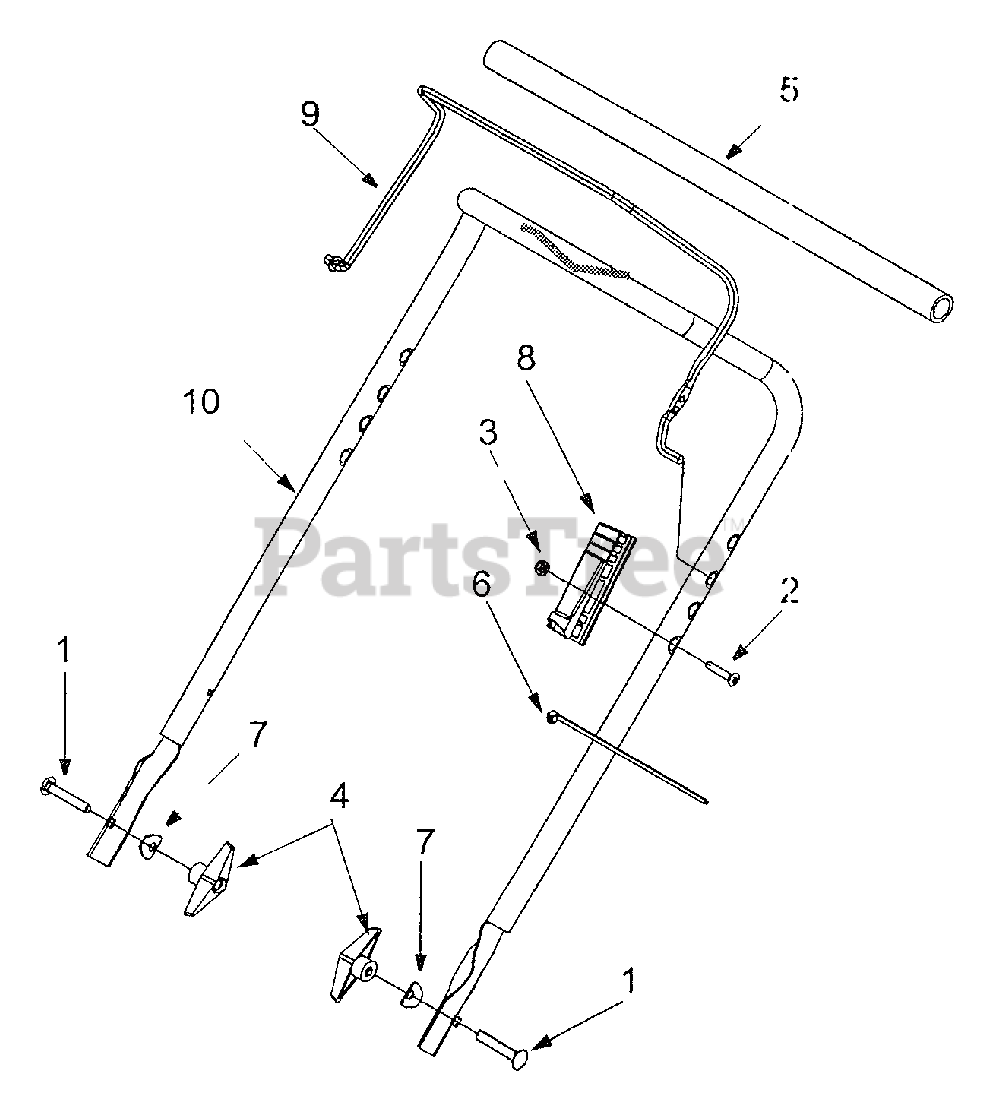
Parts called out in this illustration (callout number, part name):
1	Carriage Screw 5/16-18 x 2.0
2	Oval C-Sunk Screw 1/4-20 x 1.31
3	Hex Lock Nut 1/4-20
4	Handle Knob
5	Foam Grip Handle
6	Cable Tie
7	Saddle Washer
8	Cable Housing
